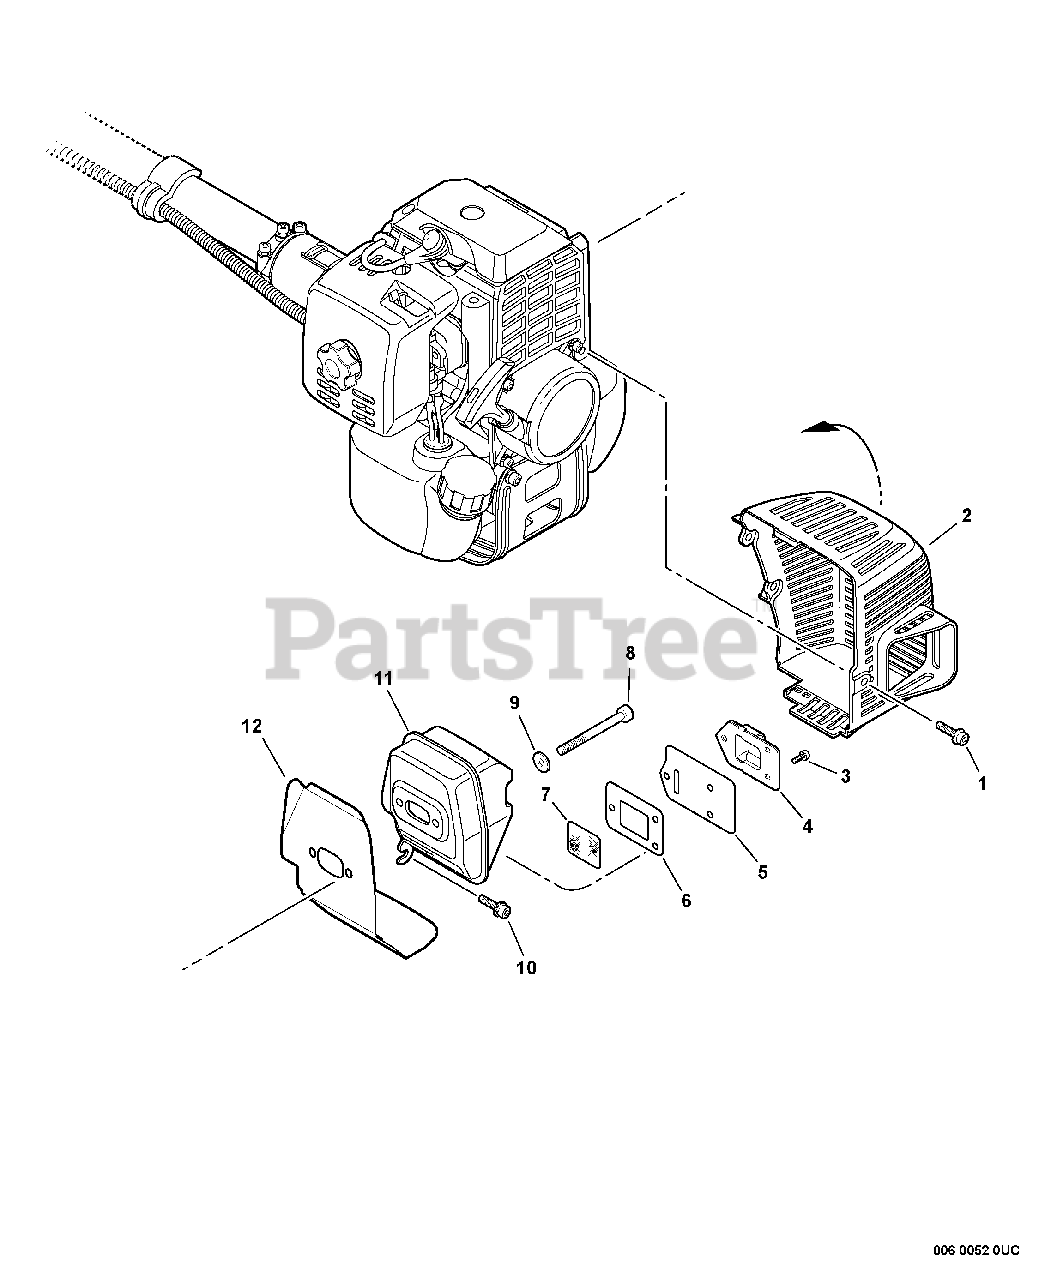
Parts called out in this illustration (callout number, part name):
1	BOLT 5×14
2	COVER, MUFFLER
3	SCREW 4×12
4	GUIDE, EXHAUST
5	GASKET, EXHAUST
6	GASKET, EXHAUST
7	SCREEN, SPARK ARRESTER
8	BOLT 5×60
9	WASHER, FLAT 5.5×10×0.8
10	SCREW 4×10
11	MUFFLER
12	SHIELD, EXHAUST
